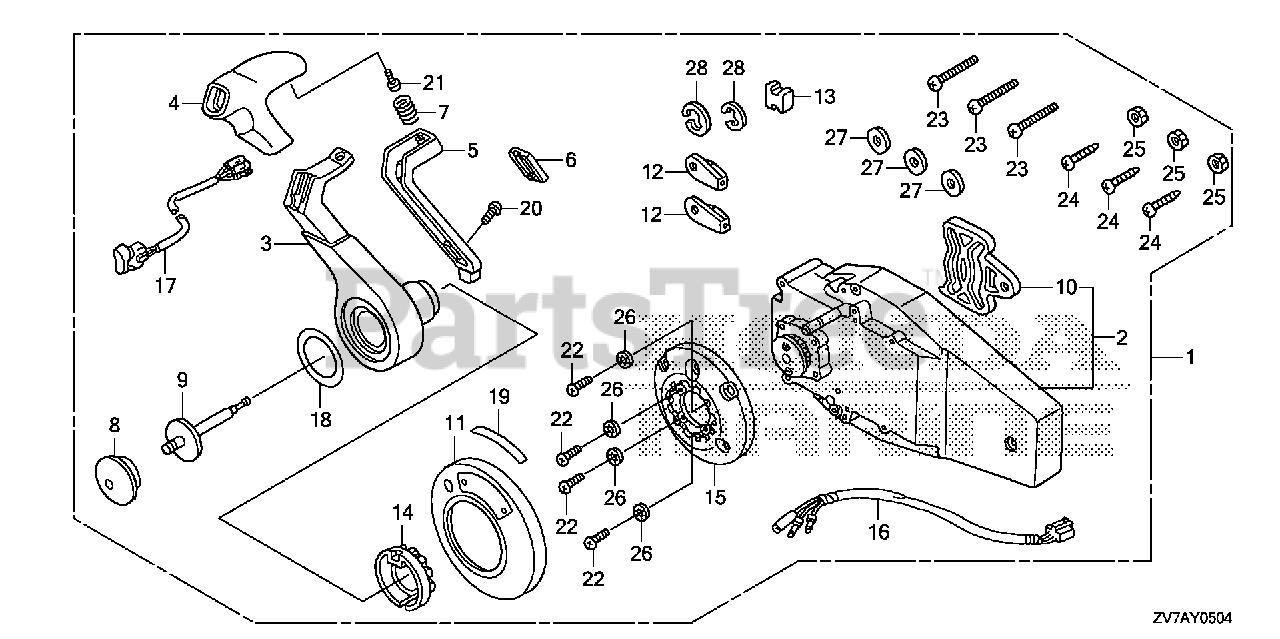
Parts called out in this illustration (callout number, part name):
1	BOX KIT, REMOTE CONTROL (FLUSH MOUNT)(R)
2	HOUSING ASSY., R. (INNER) (FLUSH MOUNT)
3	HANDLE, REMOTE CONTROL
4	COVER, GRIP
5	ARM, NEUTRAL LOCK
6	COVER, LOCK ARM
7	SPRING, NEUTRAL LOCK ARM
8	BUTTON, THROTTLE
9	SHAFT, THROTTLE BUTTON
10	PLATE, DWELL
11	COVER ASSY.
12	TERMINAL, CABLE
13	SPACER, CABLE CLAMP
14	HOLDER, NEUTRAL LOCK
15	BASE
16	SUB-HARNESS ASSY., POWER TRIM-TILT (C)
17	SWITCH ASSY., POWER TRIM-TILT (C)
18	MARK, HANDLE FLUSH MOUNT
19	MARK, FLUSH MOUNT
20	SCREW, TRUSS (4X12)
21	SCREW, PAN (5X16)
22	SCREW, PAN (5X30)
23	SCREW, PAN (6X35)
24	SCREW, TAPPING (6X30)
25	NUT, HEX. (6MM)
26	WASHER, LOCK (5MM)
27	WASHER, PLAIN (6MM)
28	E-RING (6MM)
